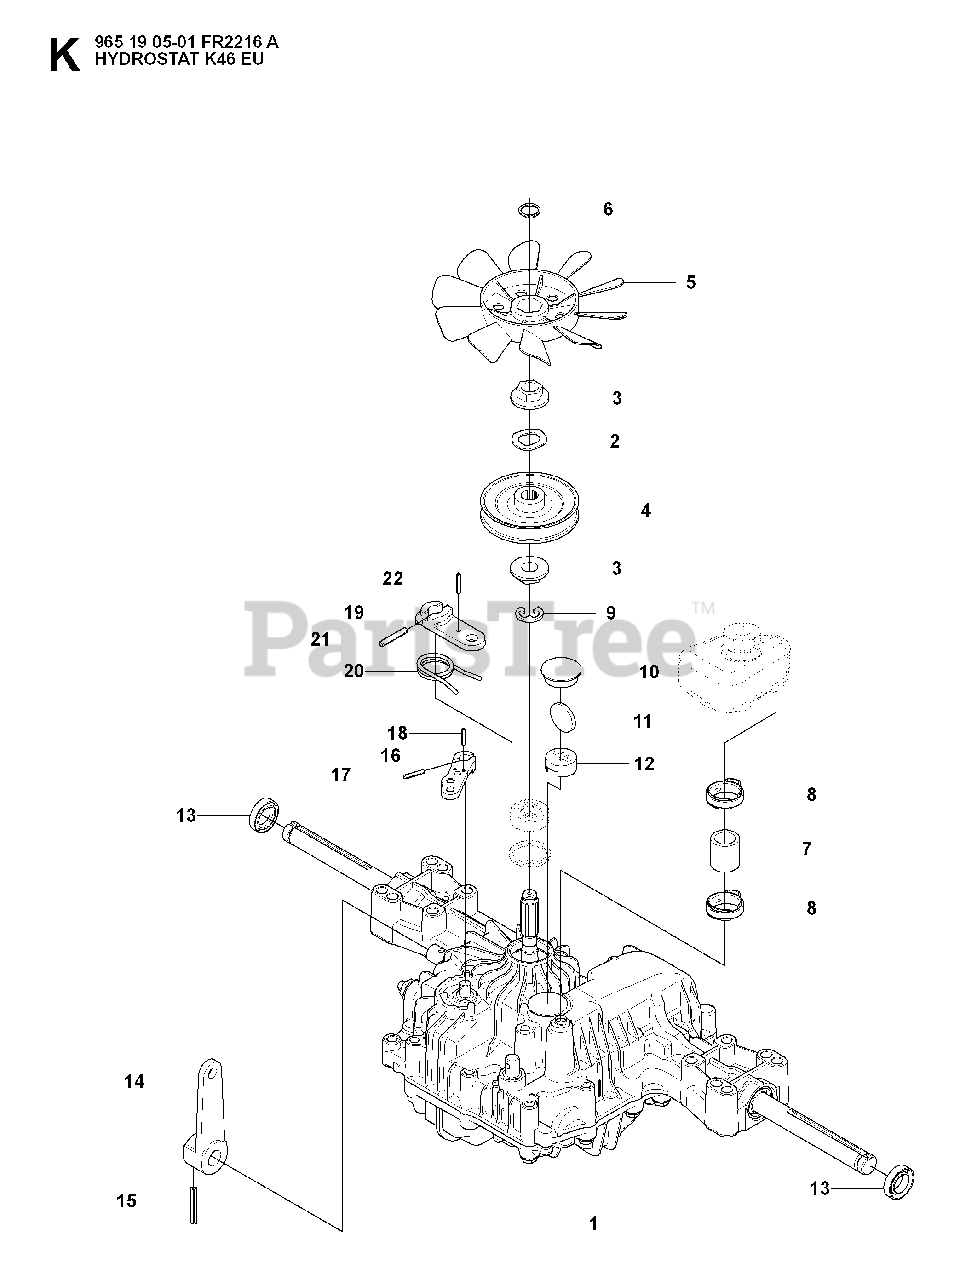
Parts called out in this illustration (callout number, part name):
1	HYDROSTAT
2	WASHER **
5	FAN
6	RETAINING RING **
8	CLAMP
12	MAGNET HOLDER
13	SEALING
14	CONTROL LEVER
20	RETURN SPRING
